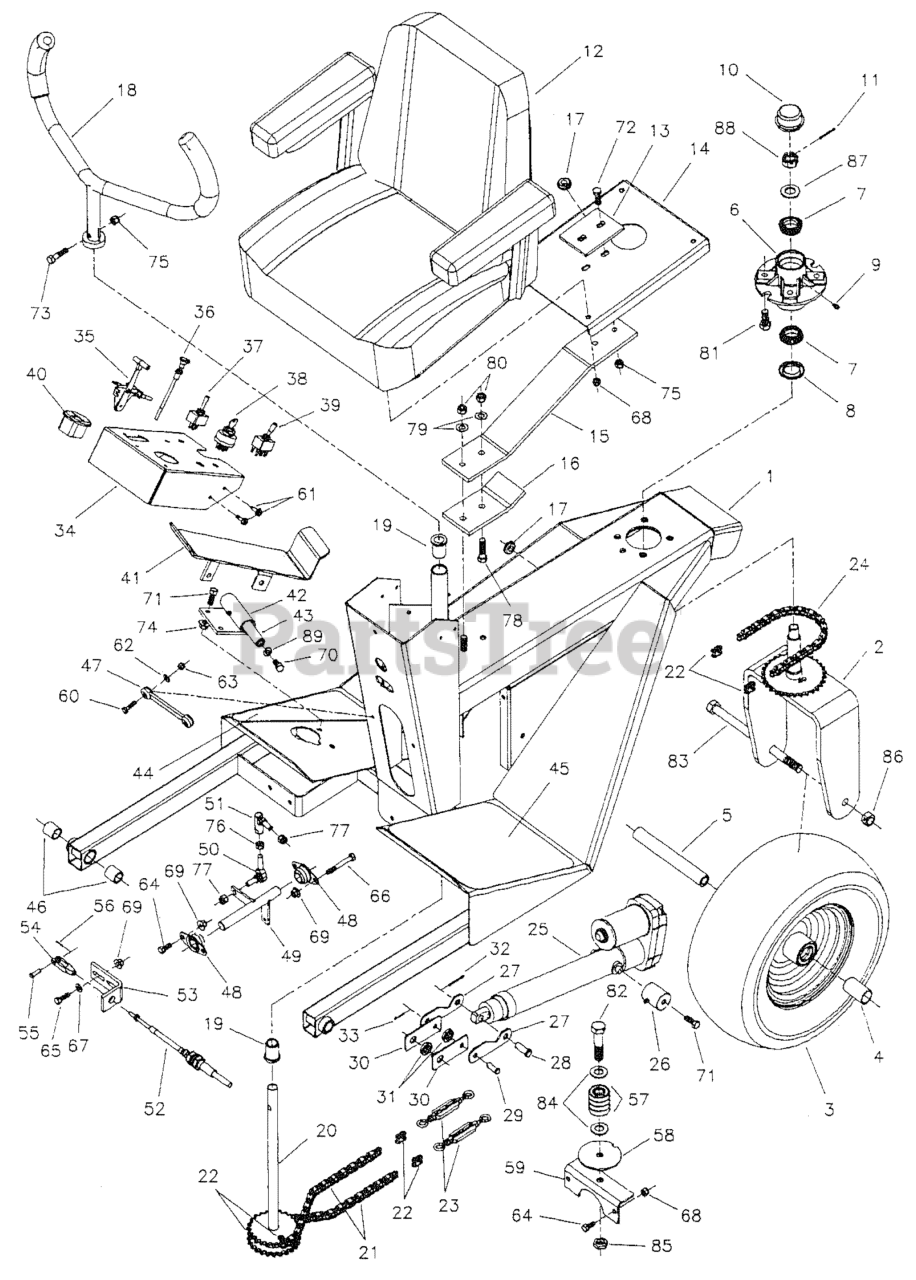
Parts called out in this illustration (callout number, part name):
1	Trailer Weldment
2	Mount, Steering Tire
3	Tire, Steering
4	Spacer, Axle
5	Axle, Steering Tire
6	Hub, Steering
7	Bearing, Tapered Roller
8	SEAL, GREASE
9	Grease Fitting
10	Cap, Dust
11	PIN, COTTER, 1/8 X 1-1/4
13	Support, Seat Plate
14	Plate, Seat
15	Spring, Seat
16	Support, Seat Spring
17	Grommet, 1/2
18	Steering Handle Assembly
18	Grip, Foam
18	Collar, I Split
19	Bushing, Flange
20	Shaft, Steering Sprocket
21	Chain, Roller - 31 Links
22	Connector, Chain Link
23	Turnbuckle
24	Chain, Roller - 35 Links
25	Actuator, Electric Lift
26	Mount, Actuator
27	Link, Actuator Lower
28	Pin, Clevis
29	Pin, Clevis
30	Link, Actuator
31	Spacer, Blade
32	PIN, COTTER, 1/8 X 1-1/4
33	PIN, 3/32 X 0.750, COT, ZINC/CLEAR
35	Cable, Throttle
36	CABLE, CHOKE CONTROL, 45
37	Switch, Actuator
38	SWITCH, IGNITION, 6 POST
39	Switch, Electric Clutch
40	Hour Meter
41	Pedal, Foot Control
41	Safety Walk
42	Mount, Foot Pedal
42	Bushing, Brass
43	Shaft, Pedal Pivot
44	Safety Walk -Right
45	Safety Walk -Left
46	Bushing, Plastic
47	Strap, Rubber
48	Bearing, Bronze Flange
49	Bell Crank
50	Ball Joint, 3/8 Male Studded
51	Ball Joint, 3/8 Female Studded
52	Cable, Speed Control
53	Bracket, Cable
55	Pin, Clevis
56	Pin, Cotter
57	Bearing, Roller
58	Wasber, Chain
59	Mount, Chain Roller
60	BOLT, 1/4-20 X 1" GD5 CZ
61	Bolt, 1/4-20 x 3/4 Self Tapper
62	WASHER, 1/4 SAE
63	NUT, 1/4-20 HEX NYLON LOCK
64	BOLT, 5/16-18 X 3/4 GD5
65	Bolt, 5/16-18 x I GD.5
66	Bolt, 5/16-18 x 2-1/2 GD.5
67	WASHER, 5/16" SAE
68	Nut, 5/16-18 Hex Nylon Lock
69	NUT, 5/16-18 HEX SERRATED FLANGE (LARGE)
70	BOLT, 3/8-16 X 3/4" GD5 CZ
71	BOLT, 3/8-16 X 1" GD5 CZ
72	BOLT, 3/8-16 X 1-1/4" GD5 CZ
73	BOLT, 3/8-16 X 1-1/2" GD5 CZ
74	Nut, 3/8-16 Serrated Flange
75	NUT, 3/8-16 HEX NYLON LOCK
76	Nut, 3/8-24 Hex
77	Nut, 3/8-24 Hex Nylon Lock
78	Bolt, 7/16-20 x 1-3/4 GD.8
79	Washer, 7/16 SAE
80	Nut, 7/16-20 Hex Nylon Lock
81	BOLT, 1/2-20 X 1-1/4" GD5 CZ
82	BOLT, 5/8-11 x 3" GD5 CZ
83	Bolt, 5/8-11 x 9-1/2 GD.5 Plain
84	Washer, 5/8 SAE
85	Nut, 5/8-11 Hex Nylon Jam
86	Nut, 5/8-11 Hex Side Lock
87	WASHER, 3/4 SAE
88	Nut, 3/4-16 Hex Slotted
